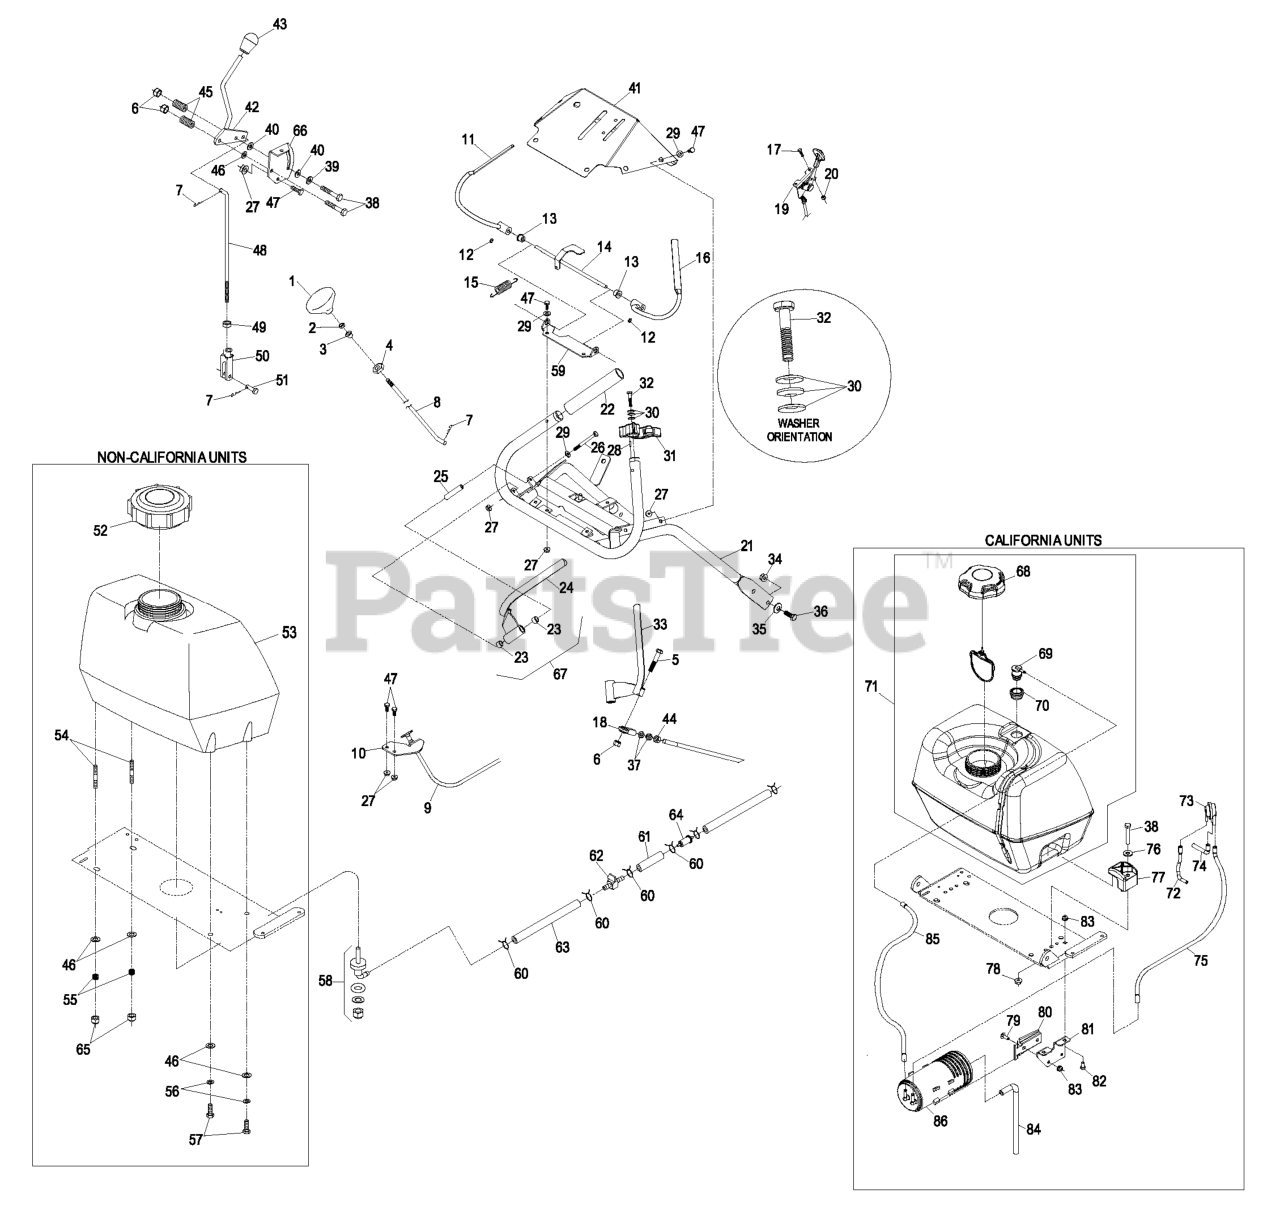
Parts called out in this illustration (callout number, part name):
1	KNOB-PUSH / PULL
2	NUT-JAM
3	BEARING-NYLON
4	NUT-PUSH
5	SCREW-HH
6	NUT-LOCK, NI
7	PIN-COTTER
8	LINKAGE,BLADE PUSH/PULL
9	CABLE-CHOKE
10	BRACKET-CABLE, CHOKE
12	SCREW-SET
13	BUSHING-NYLON
14	WLD,OPC LEVER AXLE
15	SPRING-EXTENSION
17	BOLT-CARR
18	JOINT-BALL, END
19	CONTROL, THROTTLE
20	NUT-LOCK, NI
21	WLD,VH ECS HANDLE
22	GRIP-BAR, HANDLE
23	BUSHING-SLEEVE
25	BUSHING-LEVER, DRIVE
26	SCREW-HH
29	WASHER-FLAT
30	WASHER-SPRING
31	ASM,LATCH RH THUMB
32	SCREW-HH
34	NUT-HHF, WHIZ
35	WASHER-BELLEVILLE
36	SCREW-HH
37	NUT-HJ
38	SCREW-HH
39	WASHER-FRICTION
40	WASHER-FRICTION
41	ASM,CONSOLE W/DECALS
43	KNOB, FE.LCKG. BLACK
44	NUT-HEX
45	SPRING-COMPRESSION
46	WASHER-PLAIN
47	SCREW-HH
48	ROD-CONTROL, SPEED
49	NUT-JAM
50	YOKE-ADJUSTABLE
51	PIN-CLEVIS
52	CAP-FUEL, GAS
53	ASM,FUEL TANK W/B
54	STUD
55	SPRING-TANK, FUEL
56	WASHER-LOCK
57	SCREW-HH
58	FITTING-FUEL, BULKHEAD
59	BRACKET,OPC AXLE
61	HOSE-FUEL
62	VALVE-FUEL
63	HOSE-FUEL
64	Pn 41019-1055 Filter W/6" Fuel Line
65	NUT-LOCK, NI
66	BRACKET,SHIFTER SLIDE (PL
67	DRIVE LEVER-ASM, RH
72	HOSE-VENT, FORMED
73	VALVE-CONTROL, VACUUM
74	HOSE-VENT, FORMED
75	HOSE-VENT, FORMED
76	WASHER-FLAT
78	NUT-HF, NI
79	SCREW-HH
80	BRACKET-CANISTER, CARBON
81	BRACKET-CANISTER, CARBON
82	BOLT-CARR
84	HOSE-VENT, CANISTER
85	HOSE-VENT
86	CANISTER-CARBON, 800CC
